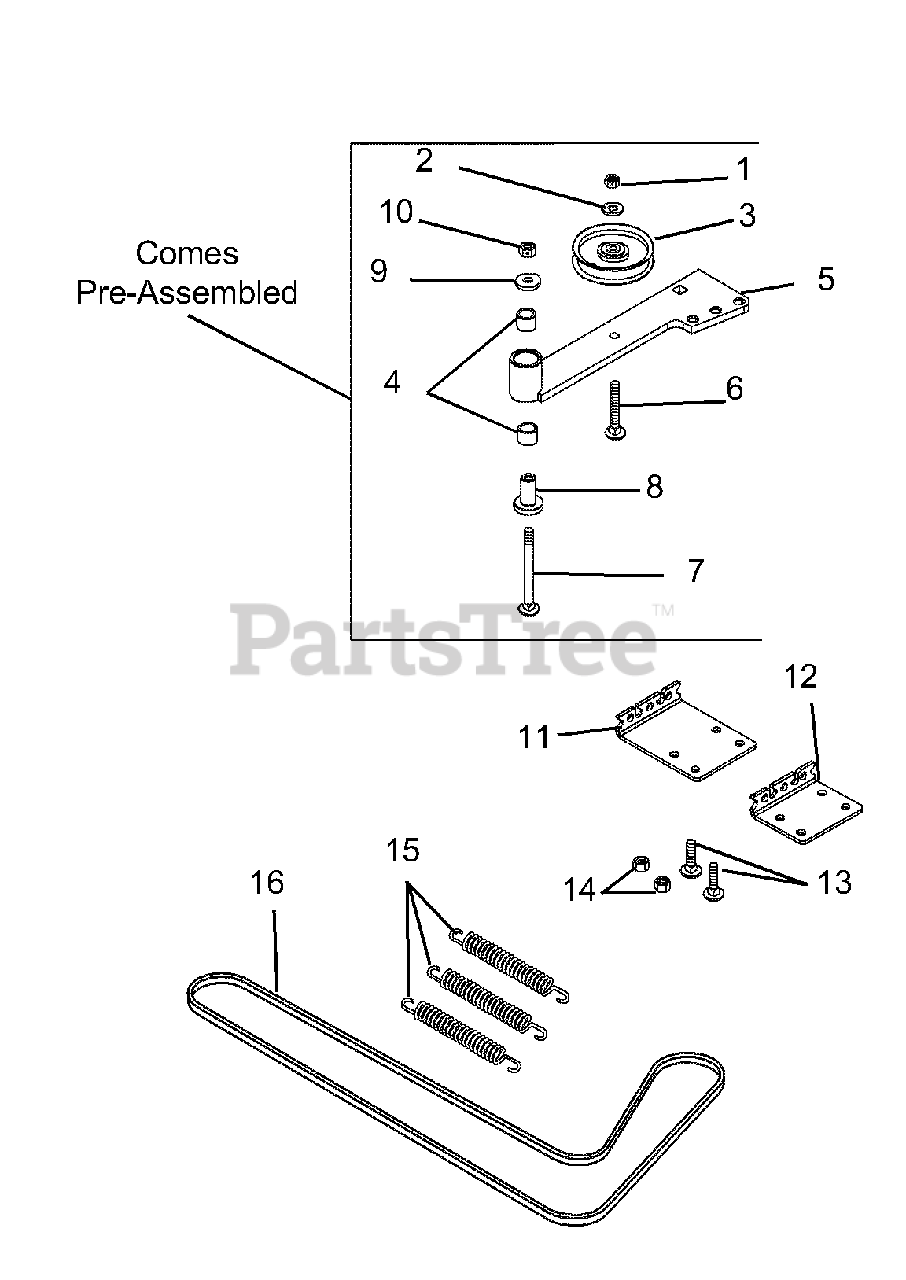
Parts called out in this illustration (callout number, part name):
1	3/8" Center Lock Nut
2	3/8" 1-1/8" x 1/16" Flat Steel Washer
3	Idler
4	Bearing
5	Idler Pivot Arm
6	3/8" x 2-3/4" Round Head Square Neck Bolt
7	1/2" x 3-1/2" Round Head Square Neck Bolt
8	Pedestal Bearing
9	17/32" x 1-1/4" x 1/10" Flat Steel Washer
10	1/2" Top Flange Lock Nut
11	Long Spring Bracket
12	Short Spring Bracket
13	3/8" x 3/4" Round Head Square Neck Bolt
14	3/8" Top Flange Lock Nut
15	Extension Spring
16	52-Inch V-Belt (Kit#: 592065)
16	60-Inch V-Belt (Kit#: 592050)
16	60-Inch V-Belt (Kit#: 592065)
16	60-Inch V-Belt (Kit#: 592051)
